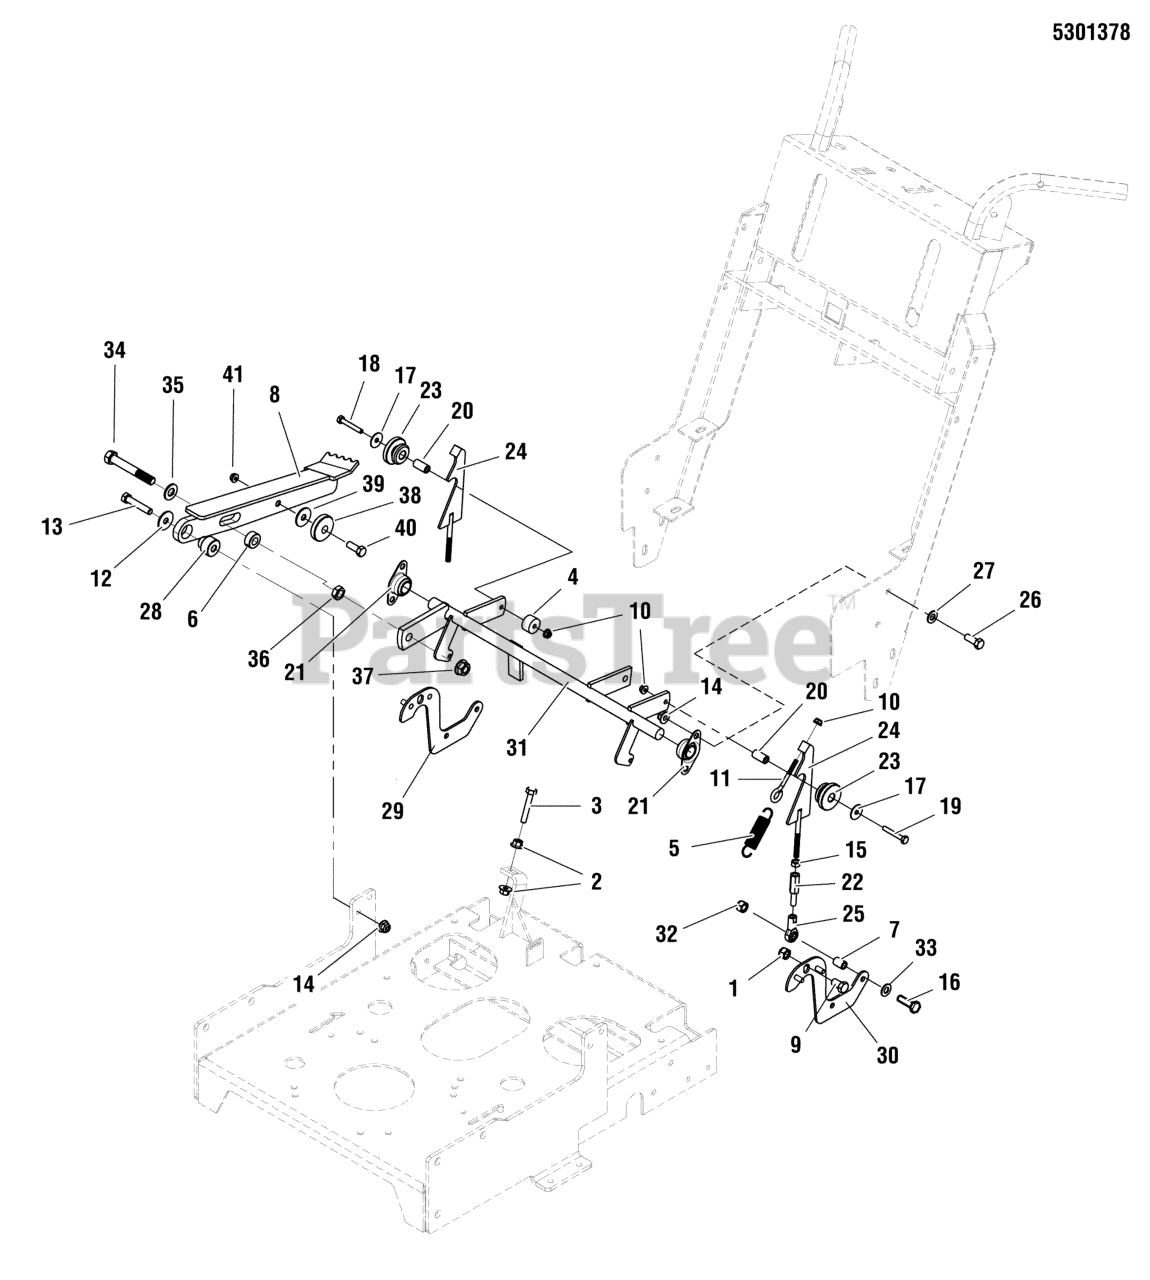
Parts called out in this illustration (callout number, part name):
1	NUT, 7/16-14 HEX TOP LOCK
2	NUT, .31-24 HEX FLG SERRATED LK
3	BOLT, 5/16-24 X 1-3/4, FULL THRD, GD5 YZ
4	SPACER, .26 X .50 X .50 YZ
5	SPRING, EXTENSION, 3.281 X .751 X .075 WIRE
6	COLLAR, 1/2 SET (1/2 SPLIT COLLAR IN MODEL)
7	SPACER, .33 X .63 X 1.00, YZ
8	WELD, FOOT PEDAL, SW30 - RED
9	BOLT, 7/16-14 X 3/4, GD 5 YZ
10	NUT, 1/4-20 Hex Nylock Flange
11	EYE BOLT, 1/4-20 X 3, ZC
12	WASHER, .390 X 1.50 X .109, YZ
13	BOLT, 3/8-16 X 2, GD5, CZ
14	NUT, 3/8 - 16 HEX NYLOCK FLANGE
15	NUT, 5/16-24 HEX, LH
16	BOLT, 5/16-18 X 2-1/4" GD5 YZ
17	WASHER, 1/4" Fender
18	BOLT, 1/4-20 X 2-1/4 GD5 CZ
19	BOLT, 1/4 X 20 X 1-3/4 GD5 YZ
20	SLEEVE, CRUISE CONTROL, ROLLER
21	BEARING, BRONZE FLANGE, 3/4"
22	ADJUSTER, ROD LINKAGE 5/16-24
23	ROLLER, SPEED CONTROL
24	ROD, CONTROL RAMP
25	BALL JOINT 5/16-24 RH FEMALE BRONZE RACE
26	BOLT, 3/8-16 X 1" GD5 CZ
27	WASHER, 3/8 SAE
28	SPACER, .38 X 1.13 X .781 STEP, CZ
28	SPACER, .38 X 1.13 X 1.00 STEP, YZ
29	WELD, CONTROL ARM - LH - RED
30	WELD, CONTROL ARM - RH - RED
31	WELD, CONTROL SHAFT - RED
32	NUT, 5/16-18 HEX NYLOCK FLANGE NUT
33	WASHER, 5/16" SAE
34	BOLT, 1/2-13 X 3-1/2, HEX HD, GD5, CZ (SV)
35	WASHER, 1/2 SAE
36	NUT, Hex, Jam, 1/2-13
37	NUT, Hex Flange, Nylock, 1/2-13
38	SPACER, .34 X 1.54 X .25 - UHMW
39	WASHER, .34 X 1.25 X 10 GA
40	SCREW, 5/16-18 X 1-1/4, FSHS, BLK, ALLEN
41	NUT, 5/16-18 HEX NYLOCK FLANGE NUT
